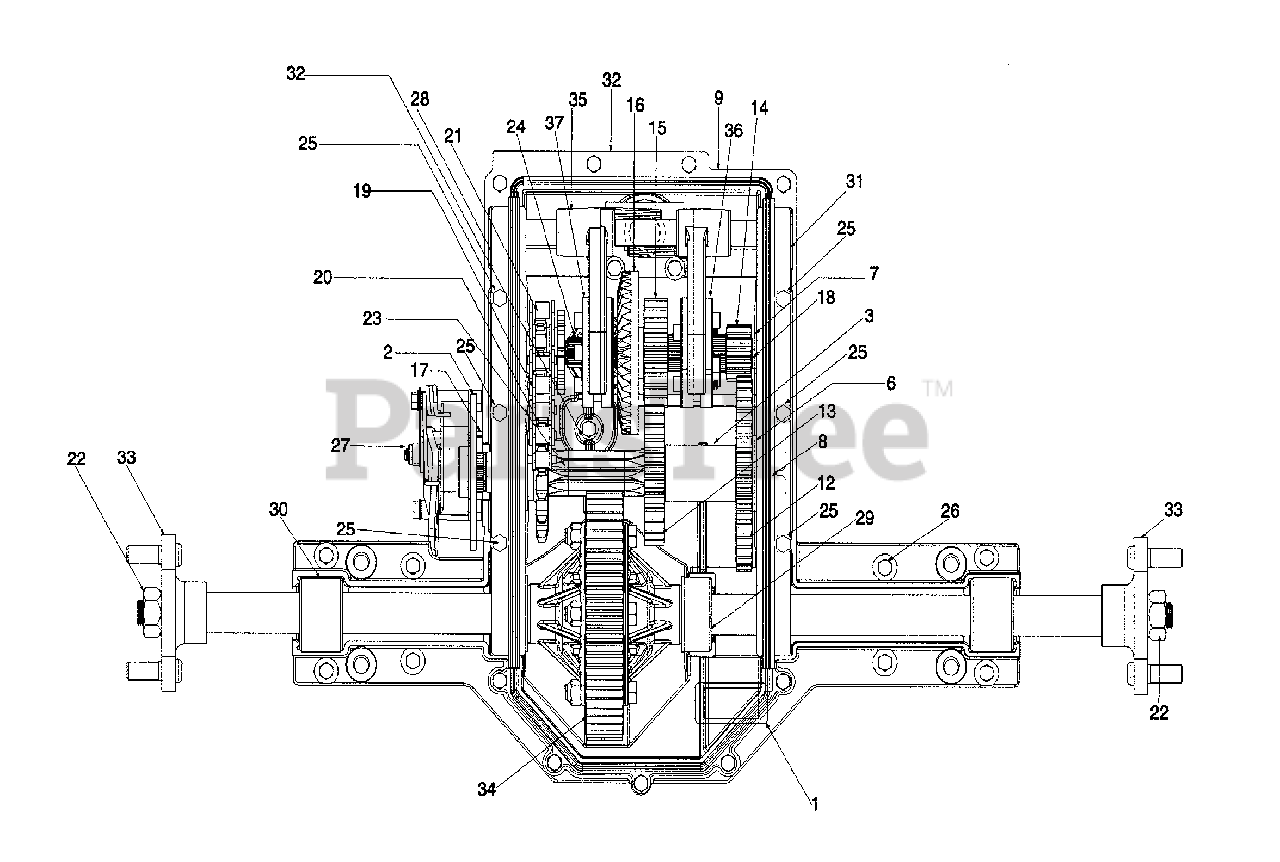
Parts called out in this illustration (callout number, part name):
1	Model I.D. Label
2	Disc Brake
3	Spacer 1.13" I.D. x 1.38" O.D.
6	Stop Washer
7	Fl-Wash. 5/8" I.D. x 1" O.D.
8	Gasket
9	Main Gasket
12	Spur Gear 37T
13	Spur Gear 27T
14	Spur Gear 10T
15	Spur Gear 20T
16	Spur Gear 41T
17	Brake Puck
18	Snap Ring
19	Chain Endless
20	Sprocket 16T
21	Sprocket 9T
22	Lug Nut 5/8-18 Thd.
23	Output Shaft-R.H.
24	Drive Shaft
25	Hex Wash. Hd. TT-Tap Scr.1/4-20 x 2.62" Lg.
26	Hex Wash. Hd. TT-Tap Scr.1/4-20 x .75" Lg.
27	Brake Ass'y.-R.H.
28	Bearing Block Ass'y.-R.H.
29	Bearing Block Ass'y.-Inner
30	Bearing Block Ass'y.-Axle
31	Bearing Block Ass'y.-L.H.
32	Housing Ass'y.
33	Hub Ass'y.-Wheel
34	Differential Ass'y.
35	Shift Fork Ass'y.
36	Collar Ass'y.-Hi-Lo
37	Collar Ass'y.-Reverse
